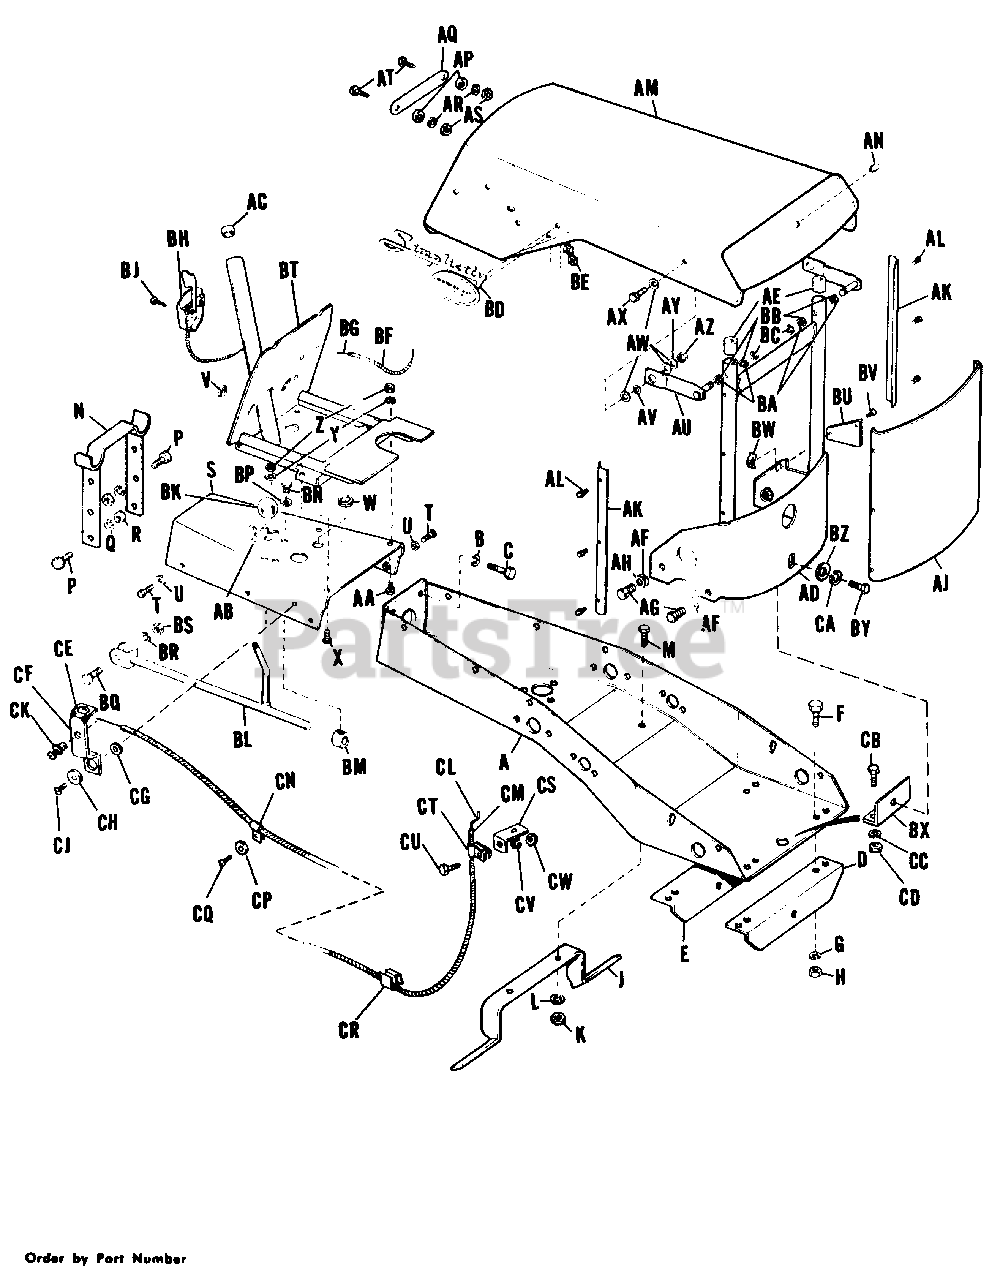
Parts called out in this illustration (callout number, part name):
A	Frame Assembly
B	Washer, Lock,7/16"
C	Screw, Cap, Hex., 7/16"-14 N.C. x 1-1/2" lg.
D	Angle, Frame, Front
E	Angle, Frame, Rear
F	Screw, Cap, Hex., 3/8"-16 N.C. x 7/8" lg.
G	Washer, Lock, 3/8"
H	Nut, Hex., Full, 3/8"-16 N.C.
J	Foot Rest
K	Nut, Hex., Full, 3/8"-16 N.C.
L	Washer, Lock, 3/8"
M	Screw, Cap, Hex., 3/8"-16 N.C. x 1" lg.
N	Support Assembly, Seat
P	Screw, Cap, Hex., 5/16"-18 N.C. x 1" lg.
Q	Washer, Lock, 5/16"
R	Nut, Hex., Full, 5/16"-18 N.C.
S	Cover Assembly, Frame
T	Screw, Recessed, Hex., 1/4"-28 x 7/8" lg.
U	Washer, Lock, 1/4"
V	Button, Plug
W	Grommet, Rubber
X	Screw, Cap, Hex., 1/4"-20 N.C. x 1" lg.
Y	Washer, Lock, 1/4"
Z	Nut, Hex., Full, 1/4"-20 N.C.
AA	Screw, Cap, Hex., 1/4"-20 N.C. x 3/4" lg.
AB	Decal, Shift Instruction
AD	Support Assembly, Grill
AE	Bumper, Hood
AF	Washer, Lock, 3/8"
AG	Screw, Cap, Hex., 3/8"-16 x 5/8" lg.
AH	Washer Plain 3/8"
AK	Molding Strip
AL	Screw, Self Topping #10 x 1/2" lg.
AM	Hood Assembly
AN	Button, Plug
AQ	Bar, Hood Latch
AR	Washer, Lock, 5/16"
AS	Nut, Hex., Full, 5/16"-18 N.C.
AT	Screw, Cap, Hex., 5/16"-18 N.C. x 3/4" lg.
AU	Pivot Link Assembly, Hood
AW	Washer, Plain, 3/8"
AX	Screw, Cap, Hex., 3/8"-16 N.C. x 1-1/4" lg.
AY	Washer, Lock, 3/8"
AZ	Nut, Hex., Full 3/8"-16 N.C.
BA	Washer, Plain, Nylon
BB	Washer, Plain, 3/8"
BC	Nut, Lock, Hex., Full
BD	Emblem, Simplicity
BE	Nut, Speed, Push On
BF	Cable, Throttle
BG	Wire, Throttle
BH	Control, Throttle Lever
BJ	Screw, Self Tapping, Round Slotted Head, #10-24 x 1" lg.
BL	Rod Assembly, Shifter
BN	Screw, Cap, Hex., 5/16"-18 N.C. x 3/8" lg.
BP	Washer, Lock, 5/16"
BQ	Screw, Cap, Hex., 5/16"-18 NC x 1-1/2" lg.
BR	Washer, Lock, 5/16"
BS	Nut, Hex., Full, 5/16"-18 NC
BT	Support Assembly, Steering Post
BU	Cover Plate
BV	Screw, Self Tap, #10 x 1/2" lg.
BW	Nut, Speed
BX	Bracket Assembly
BY	Capscrew, Hex, 5/16"-18 NC x 1-1/4" lg.
BZ	Washer, Plain, 5/16"
CA	Washer, Lock, 5/16"
CB	Capscrew, Hex, 5/16"-18 NC x 1" lg.
CC	Washer, Lock, 5/16"
CD	Nut, Hex, Full, 5/16"-18 NC
CE	Choke Decal
CF	Choke Lever
CG	Washer (spacer)
CH	Washer, Plain, 1/4"
CJ	Screw, Self Tap, 1/4"-20 NC x 7/8" lg.
CK	Clamp, Wire
CL	Wire, Choke
CM	Cable, Choke
CP	Washer, Plain
CQ	Screw, Self Tap, 1/4"-20 NC x 7/8" lg.
CR	Speed Clip
CU	Capscrew, Hex, 1/4"-20 NC x 1/2" lg.
CV	Washer, Lock, 1/4"
CW	Nut, Hex Full, 1/4"-20 NC
